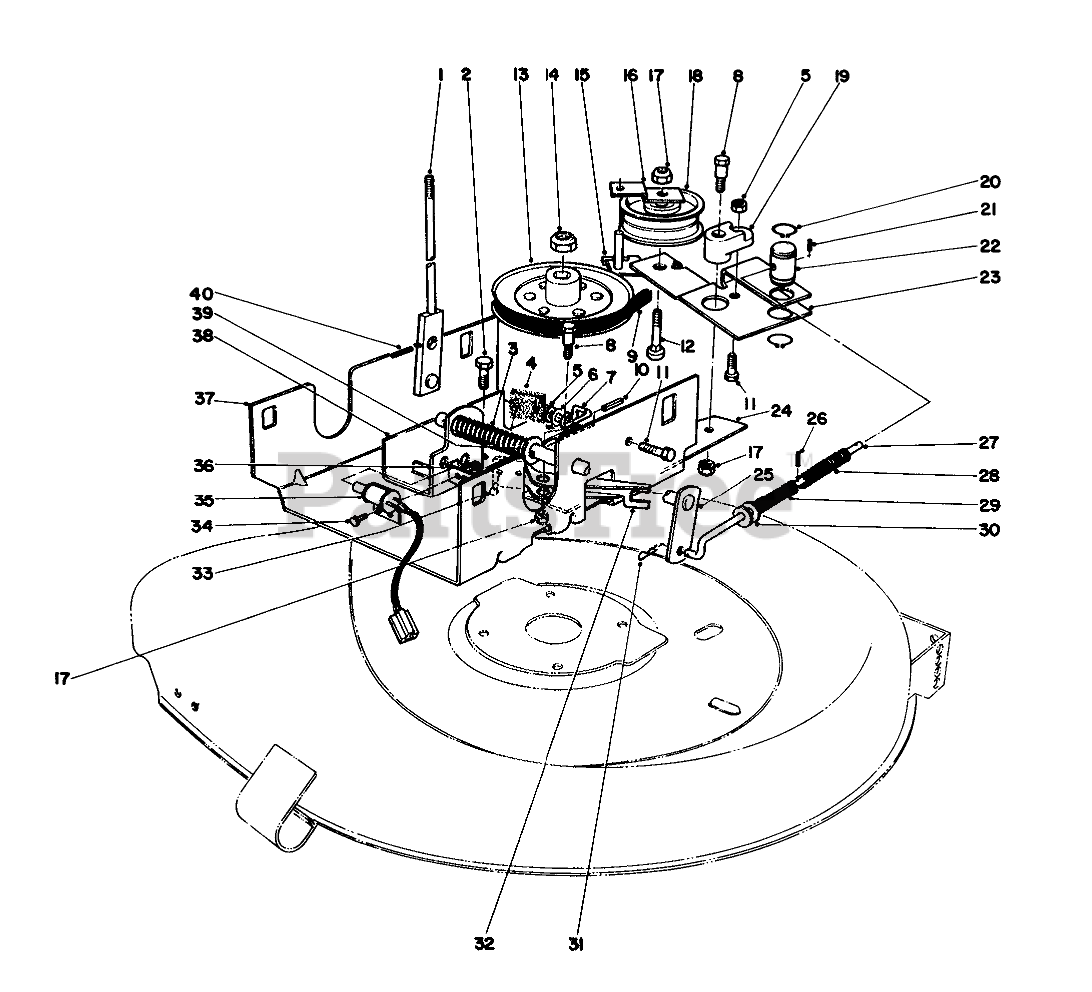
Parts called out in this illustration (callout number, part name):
1	Lever-Deck Engagement
2	SCREW-HH
3	COMP SPRING O
4	PAD-BRAKE
5	NUT-LOCK, NI
6	WASHER-FLAT
7	BELT GUIDE
8	SHOULDER BOLT
9	V-BELT
10	PIN-SPRING
11	SCREW-HH
12	SCREW-CARR
13	DECK PULLEY R
15	Retainer-Belt
16	BELT RETAINER UPPER
17	NUT-LOCK, NI
18	PULLEY-IDLER
19	BUSHING
20	RING-RETAINING
21	PIN-ROLL
22	Pin-Pivot
23	Arm-Idler
24	Bracket-Idler Mounting
25	Linkage
26	PIN-SPRING
27	BLADE ENGAGE ROD
28	Spring Deck Idler
29	Spring Deck Brake
30	WASHER
31	PIN-COTTER
32	Blade Brake (Incl. Ref. #4 & 33)
33	Rivet
35	DECK INTERLOCK SWITCH
36	NUT-KEPS
37	Channel-Height Adjustment
38	Mounting Bracket-Blade
39	WASHER-FLAT
40	PIN-SPIRAL
